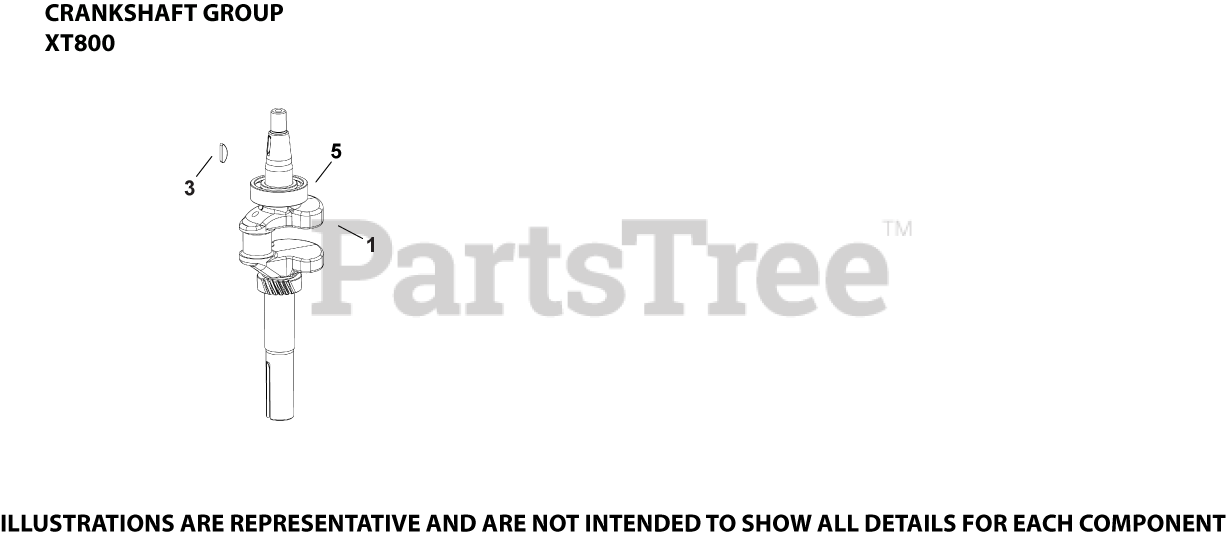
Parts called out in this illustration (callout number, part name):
1	CRANKSHAFT ASSEMBLY
3	KEY, FLYWHEEL
5	BEARING, BALL
